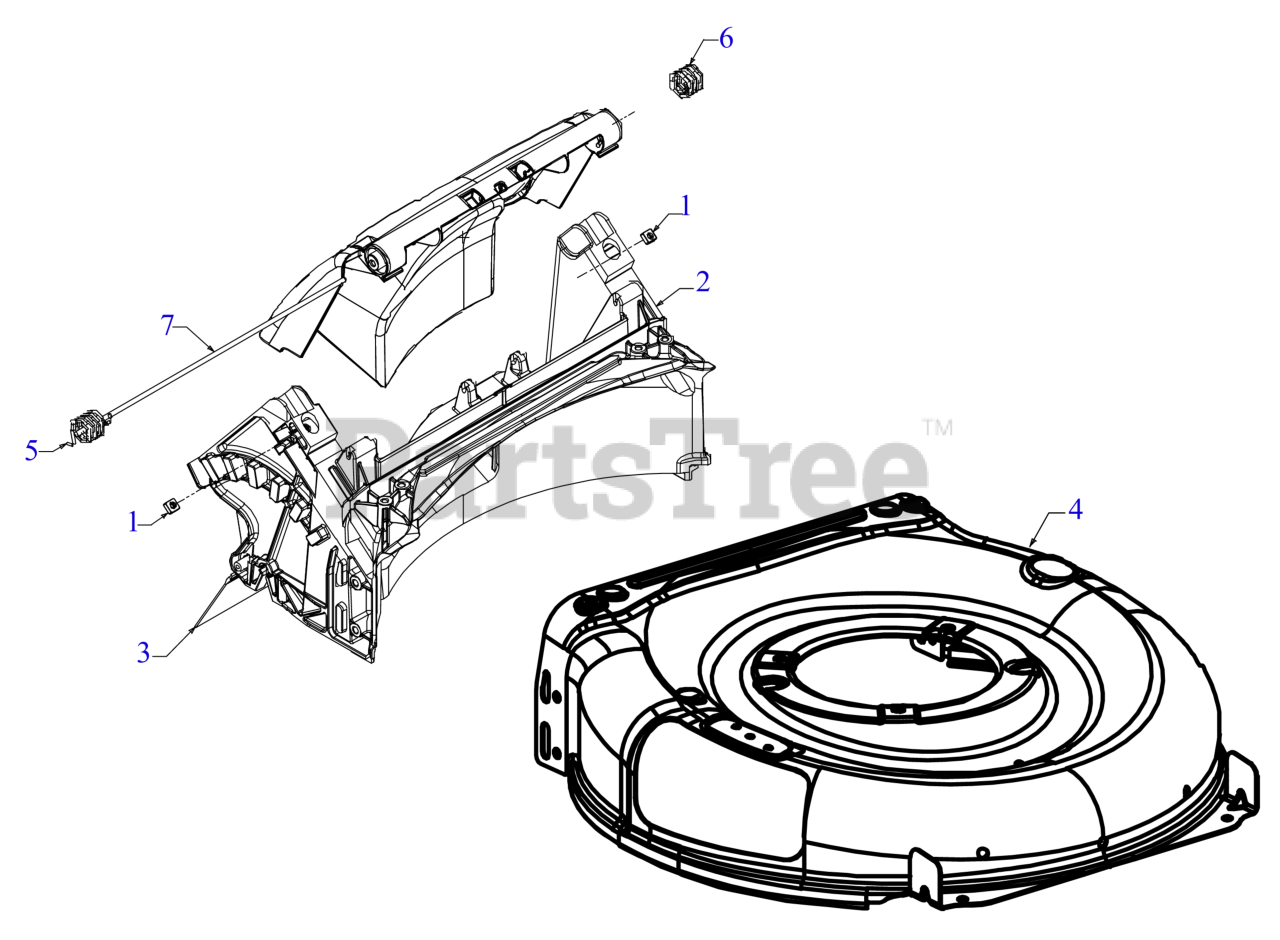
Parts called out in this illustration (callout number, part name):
1	SQUARE NUT 1/4-20
2	REAR DOOR ASSEMBLY
3	TRAILSHIELD
5	TORSION SPRING (RH)
6	TORSION SPRING (LH)
7	REAR DOOR PIVOT ROD
